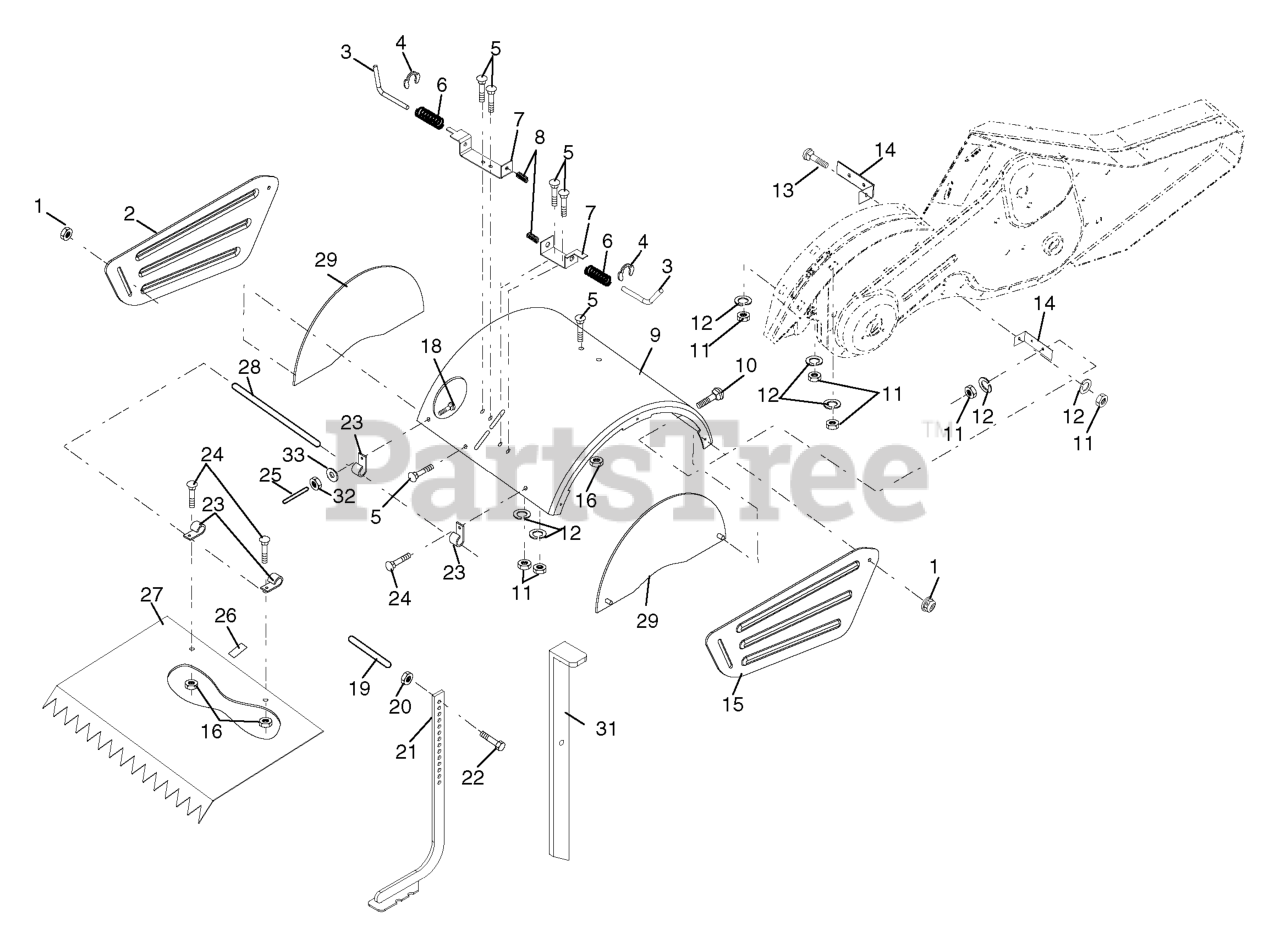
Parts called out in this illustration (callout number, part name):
1	NUT LOCK HEX FLANGE 5/16-18
2	SHIELD
3	STAKE PIN TI
4	RING, KLIP
5	BOLT, RDHD SQNK 5/16-18 X 3/4
7	BRACKET.LATCH.STAKE.3.20.BLACK
8	SPRING CRT
9	SHIELD.PNT.TINE.17"M
10	BOLT
11	NUT
12	WASHER.LOCK.HVY.HLCL.SPR.5/16
13	BOLT.CARRIAGE.5/16-18
14	BRACKET.TINE.SHIELD.TILLER
15	SIDE SHIELD RH
16	NUT T
20	NUT.HEX.3/8-16UNC
21	STAKE.DEPTH.16.CRT.BLACK
22	BOLT.375-16
24	BOLT
26	PAD IDLER TI
27	SHIELD LEVELING
28	PIN.HINGE.TILLER
29	SHIELD.ASM.SIDE.ORANGE.(OLD)
31	STAKE.PNT.DEPTH.DRAG
32	NUT
33	LOCKWASHER
